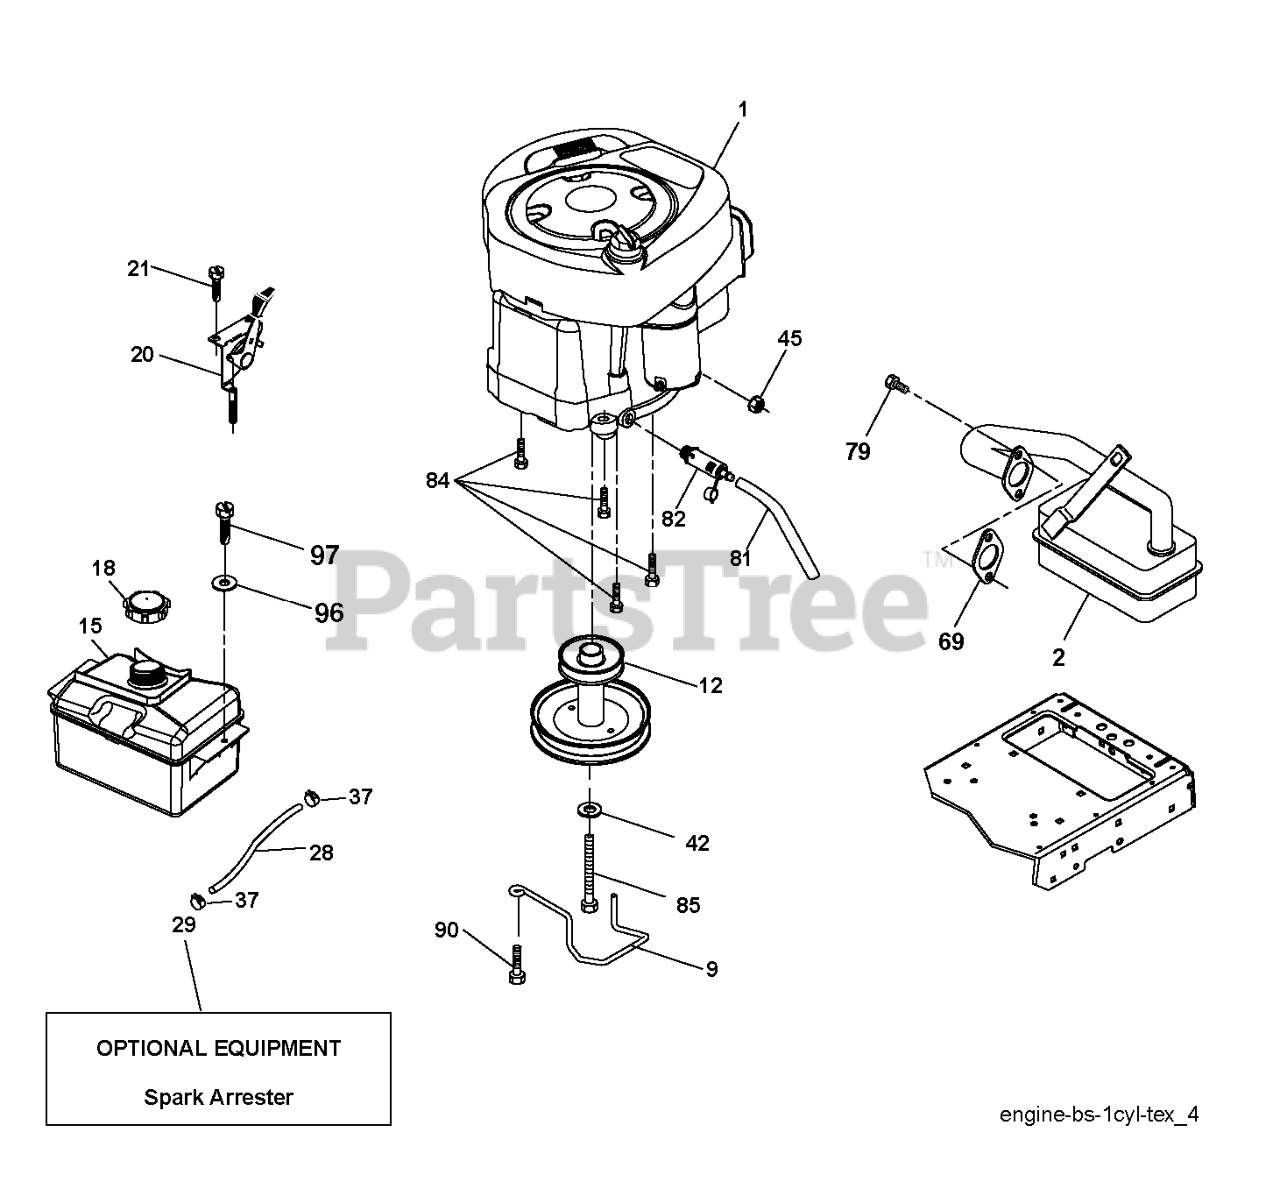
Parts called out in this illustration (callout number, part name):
2	MUFFLER.B&S.MODEL.21.11HP.OHV
9	KEEPER.BELT.ENGINE.3.25 (3 2)
12	PULLEY.ENG.CL.MECH.SLVR.LT/YT
15	RP TANK FUEL FRT 1.5 GAL
18	FUEL CAP
20	CONTROL.TH/CK.C.
21	SCREW.#10 X 0.750.BOS
28	LINE.FUEL.20
29	KIT.SPARK ARRESTOR 794945 B&S
37	HOSE CLAMP
42	LOCKWASHER
45	NUT
69	REPL BY 532 27 22-93
79	SCREW.SOCKET HD.5/16-1
81	TUBE, DRAIN OIL ASM.
82	PLUG DRAIN OIL EASY
84	SCREW.3/8-16
85	BOLT HEX 7/16-20X4-1/4"
90	SCREW 3/8-16X1
97	SCREW HEXWSHR 1/4-20X3/4
